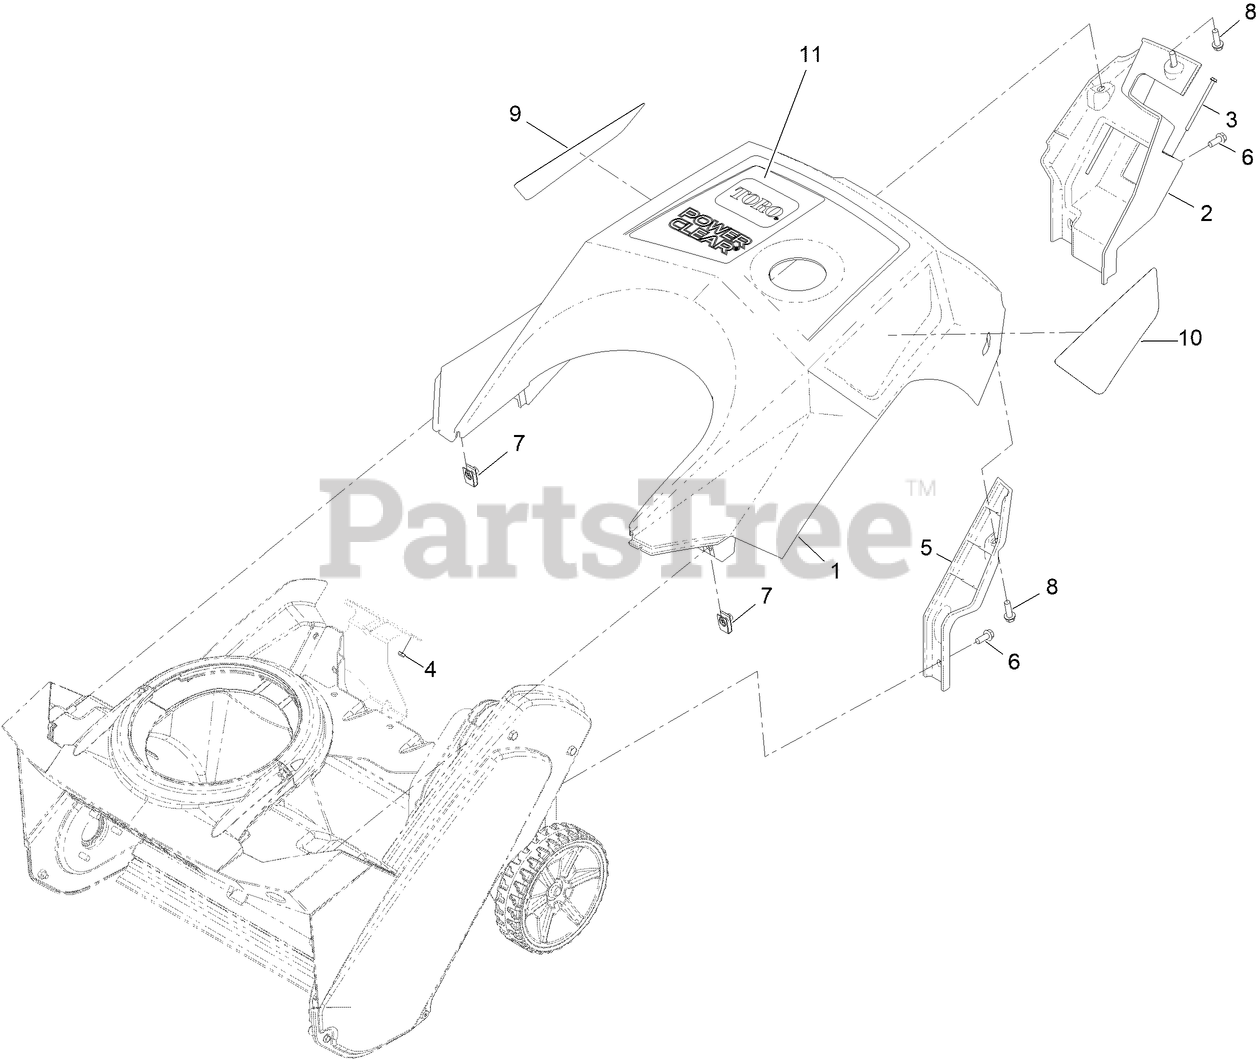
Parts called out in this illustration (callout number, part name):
1	SHROUD-UPPER
2	SHROUD-LOWER, RH
3	SCREW-HWH
4	NUT-HEX
5	SHROUD-LOWER, LH
6	SCREW-HWH
8	SCREW-PLASTITE, HWH
9	DECAL-RH SHROUD ZE
10	DECAL-LH SHROUD ZE
11	DECAL-SHROUD
